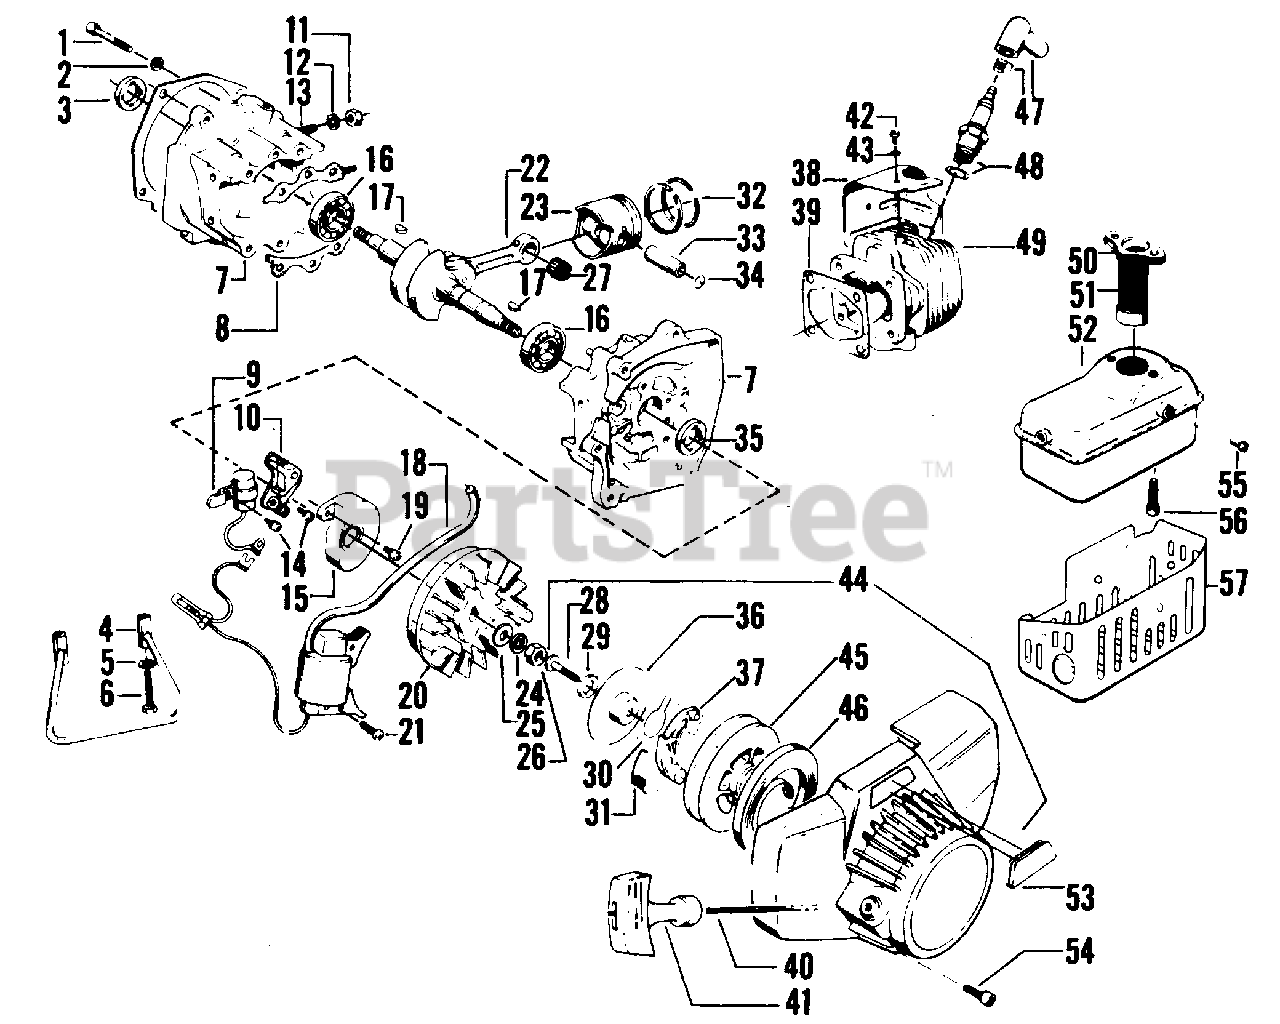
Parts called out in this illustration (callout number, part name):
2	Lockwasher
3	Oil Seal (Rear)
5	Lockwasher
7	Crankcase Complete (Incl. 3, 8, 16, 35, 39 & 56)
8	Crankcase Gasket Set
9	Condenser
10	Point Set
11	Nut, Cylinder
12	Washer, Cylinder
14	Screw & Washer Assembly
17	Woodruff Key
18	Ignition Coil
20	Flywheel
22	Crankshaft Assembly
24	Lock washer
25	Washer - Flywheel Flat
27	Needle Bearing
30	Friction Spring
31	Return Spring
32	Piston Ring
33	Piston Pin
34	Retaining Ring
35	Oil Seal (Front)
36	Friction Plate
38	Cylinder Cover
39	Cylinder Gasket
40	Starter Rope
41	Starter Handle
42	Screw - Cylinder Cover
43	Lockwasher, Cylinder Cover
44	Recoil Starter Assembly (Inc.28,29,30,31,36, 37,40,41,45,46)
45	Starter Pulley
46	Recoil Spring
47	Spark Plug Cap Assembly
48	Spark Plug (NGK B7HS)
49	Cylinder
50	Muffler Gasket
51	Screen, Spark Arrestor
52	Muffler Assembly
57	Muffler Cover Assembly
